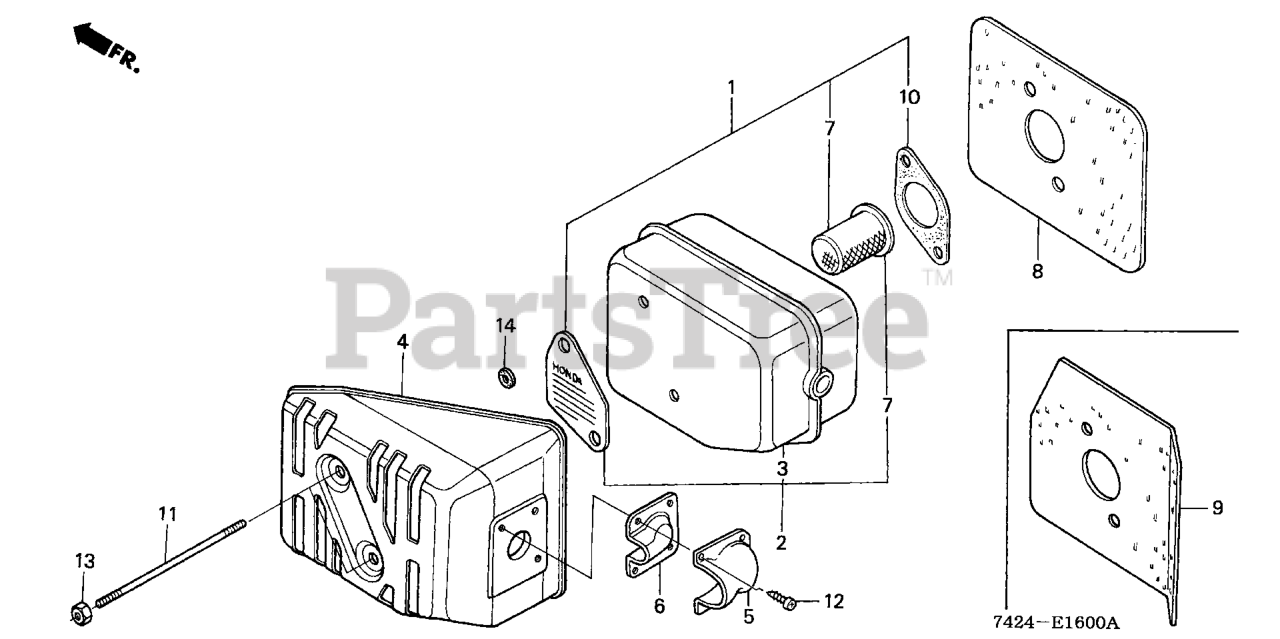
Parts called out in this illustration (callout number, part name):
1	ARRESTER KIT, SPARK
3	MUFFLER
4	PROTECTOR, MUFFLER
5	DEFLECTOR, MUFFLER
6	GUIDE, MUFFLER
7	ARRESTER KIT, SPARK
9	GASKET, MUFFLER Use from Engine SN 2195322.
10	GASKET, MUFFLER
11	BOLT, STUD (6X82)
12	SCREW, TAPPING (4X6) (TO INSTALL OPTIONAL SPARK ARRESTER)
13	NUT, SELF-LOCK (6MM)
